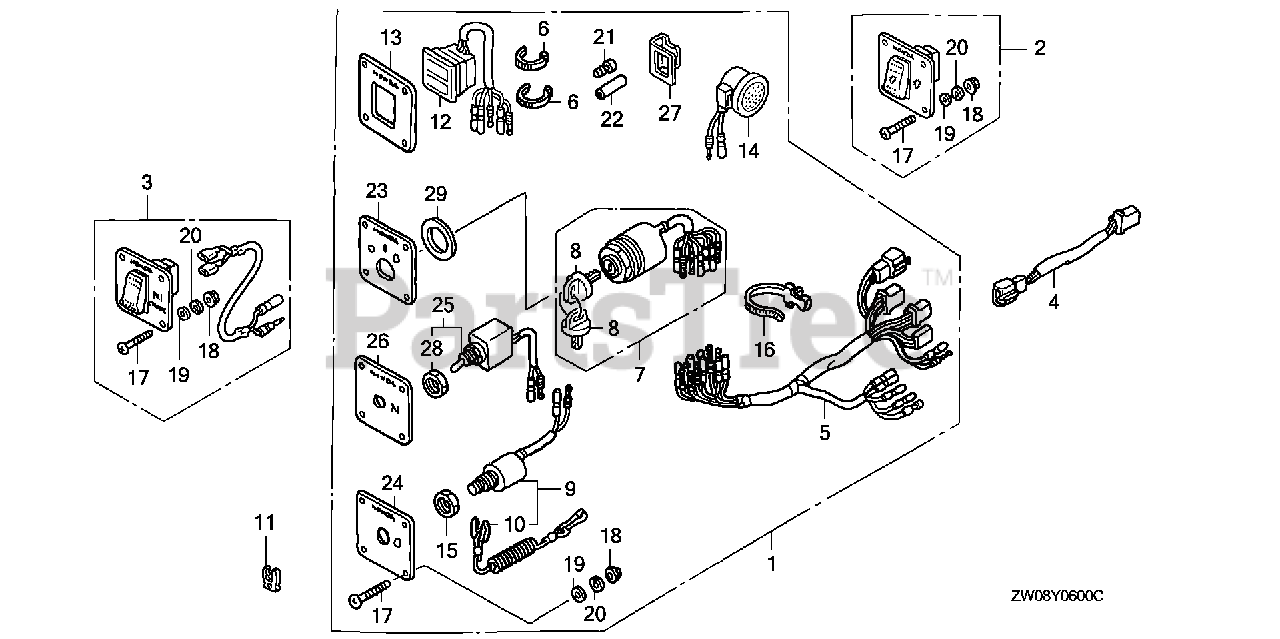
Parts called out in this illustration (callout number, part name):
1	PANEL KIT, CONTROL (B)
4	SUB-HARNESS ASSY., POWER TRIM-TILT (A)
5	HARNESS ASSY., SWITCH PANEL
6	TIE, CABLE (NATURAL 2.4X92) Use up to Frame SN 1300359.
7	SWITCH ASSY., COMBINATION DUAL QTY = (2) (SINGLE)
8	KEY ASSY., COMBINATION SWITCH (35100-ZV5-003 ONLY) DUAL QTY = (4) (SINGLE)
9	SWITCH ASSY., EMERGENCY STOP
10	WIRE, EMERGENCY (SINGLE) (DUAL)
11	CLIP, EMERGENCY LOCK
12	LAMP ASSY., INDICATOR (2-LED)
13	PANEL, INDICATOR
14	BUZZER, WARNING
15	NUT, HEX. (16MM) DUAL QTY = (2) (SINGLE)
16	BAND, WIRE HARNESS (150MM) (NATURAL) DUAL QTY = (2) (SINGLE)
17	SCREW, PAN (5X40)
18	NUT, FLANGE (5MM)
19	WASHER, PLAIN (5MM)
20	WASHER, SPRING (5MM) DUAL QTY = (8) (SINGLE)
21	PLUG, CONNECTOR (INNER) (TROLLING CONTROL)
22	PLUG, CONNECTOR (OUTER) (ENGINE NO.)
23	PANEL, SWITCH
24	PANEL, EMERGENCY STOP SWITCH
25	SWITCH ASSY., SOLENOID
26	PANEL, SOLENOID
27	BRACKET, BUZZER
28	NUT, HEX. (12MM)
29	WASHER, PLAIN
